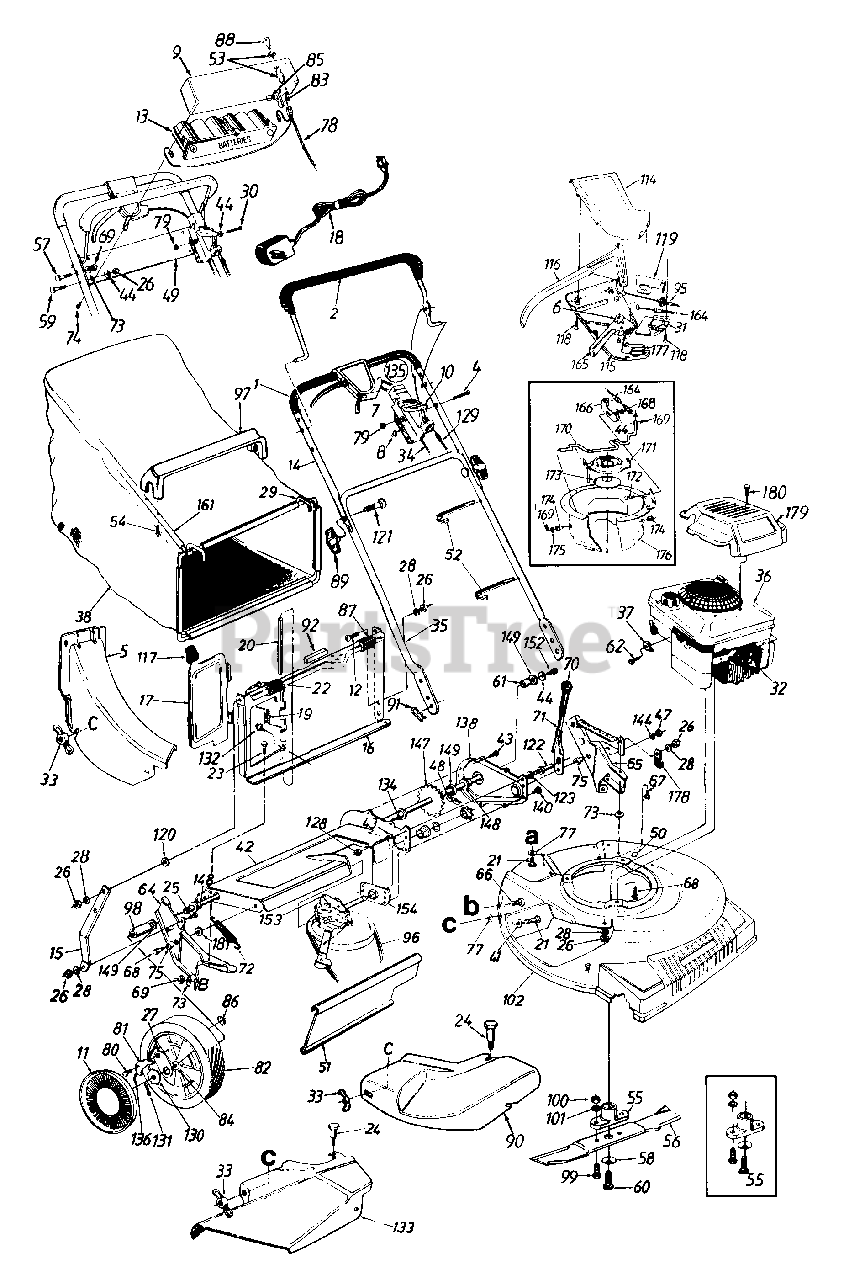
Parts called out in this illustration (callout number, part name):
1	Foam Grip
2	Control Handle
4	Oval C-Sunk Scr.
5	Rear Discharge Chute Ass'y.
6	3 Tooth Rack Gear Insert
7	Throttle Body
8	Spr. Wash..66" I.D.
9	Battery Tray
10	Throttle Lever
11	Hub Cap
12	Truss Mach. Scr. 1/4-20 x .62"
13	Battery Pack - 12 Volt
19	Torsion Spring
21	Carriage Bolt 1/4-20 x .62"
22	Truss Mach. Scr. 1/4-20 x .75"
23	Hex AB-Tap Scr. 1/4-20 x .38"
24	Shoulder Bolt Special
25	Hex Bolt 1/4-20 x .62" Lg.
26	Hex Nut 1/4-20 Thd.
27	Pawl Plate
28	L-Wash. 1/4" I.D.
30	Hex Bolt 1/4-20 x 2" Lg.
31	S.P. Control Cover
32	Spark Plug Insulator
33	Wing Nut
34	Throttle Cable 61"
36	Engine
37	Casing Clamp
38	Grass Bag
41	Fl-Wash..344" I.D. x .62"
44	Bell-Wash. 1/4" I.D.
47	Hex Patch L-Nut 3/8-24 Thd.
48	#48 Chain .500" Pitch x 30 Links
51	Rear Flap
52	Cable Tie
53	Ignition Switch
54	Hex AB-Tap Scr. #12 x 1.25"
55	Blade Adapter Kit
56	21" Mulching Blade
57	Curved Carr. Bolt 5/16-18 x 1.38" Lg.
58	Bell-Wash..46" I.D.
59	Carr. Bolt 1/4-20 x 1.25" Lg.
60	Hex Bolt 7/16-20 x 1.5"
61	Spacer .513" I.D.
62	Hex Wash. Hd. Scr. #10-32 x .62" Lg.
64	R.H. Handle Wheel Brkt. Ass'y.
65	L.H. Handle Wheel Brkt. Ass'y.
66	Carriage Bolt 5/16-18 x .62"
67	Hex B-Tap Scr. 5/16-18
68	Hex TT- Tap Scr. 3/8-16
69	Hex Nut 5/16-18 Thd.
71	Height Adj. Lever
72	Extension Spring 3.80" Lg.
73	Bell-Wash. 5/16" I.D.
74	Truss Mach. Tap Scr. 1" Lg.
75	Shld. Spacer .5" Dia.
77	Bolt Retainer 1/4 x .50" O.D.
78	Wire Harness
79	Hex L-Nut 1/4-20 Thd.
80	Shld. Scr..342" Dia. x .268
81	Pawl
82	Wheel Ass'y. Comp.
83	Plug
84	Sleeve Bearing 1/2" I.D.
85	Fuse Holder
86	Flat Nut 1/4-20 Thd.
88	Ignition Key
89	Hand Knob
90	Mulching Plug
91	Hairpin Clip
92	Foam Strip 1/4" x 1" Lg.
95	S.P. Cable - 50" Lg.
96	"V"-Belt
98	Sleeve .526" I.D.
99	Hex Bolt 3/8-24 x 1.0" Lg.
100	Hex Nut 3/8-24 Thd.
101	L-Wash. 3/8" I.D.
115	Self-Propelled Control Cover
116	Control Lever
117	Door Grip
118	Fl-"C"-Sunk Hd. Tap Scr. #10 x .75" Lg.
119	6-Speed Rack Cable Brkt.
120	Fl-Wash..285" I.D. x 1.25"
121	Curved Hd. Bolt 5/16-18 x 2" Lg.
122	Shld. Pin 1.43" Lg.
123	L-Wash. 3/8" I.D.
128	Hex Jam Nut 3/8-24 Thd.
129	Control Cable - 44"
130	Ratchet Wheel 1.62" O.D.
131	Cotter Pin 1/8" Dia. x 1"
132	Hex B-Tap Scr. #10 x .38" Lg.
133	Side Chute Deflector Ass'y.
134	Hex Flange Bearing
135	Throttle Box Comp.
136	Spring - Nylon
144	Fl-Wash..385" I.D. x .87"
147	Rear Shaft Ass'y. 21.94" Lg.
148	Hex Flange Brg..506" I.D.
149	Fl-Wash..531" I.D. x .930"
152	Hex Bolt 1/4-20 x .62" Lg.(Grade 5)
153	Transmission Comp.
164	Spd. Control Cable - 50" Lg.
165	6-Spd. Shift Lever
169	Cot-Pin 3/32" Dia. x .75" Lg.
171	Movable Pulley Half Ass'y.
172	Carr. Bolt 1/4-20 x .5" Lg.
173	Splined Pulley Half
174	Flanged Bushing
175	Fl-Wash..328" I.D. x .68" O.D.
179	Engine Cover
180	Screw #10 x 1.25" Lg.
181	Fl-Wash..383" I.D. x 1" O.D.
